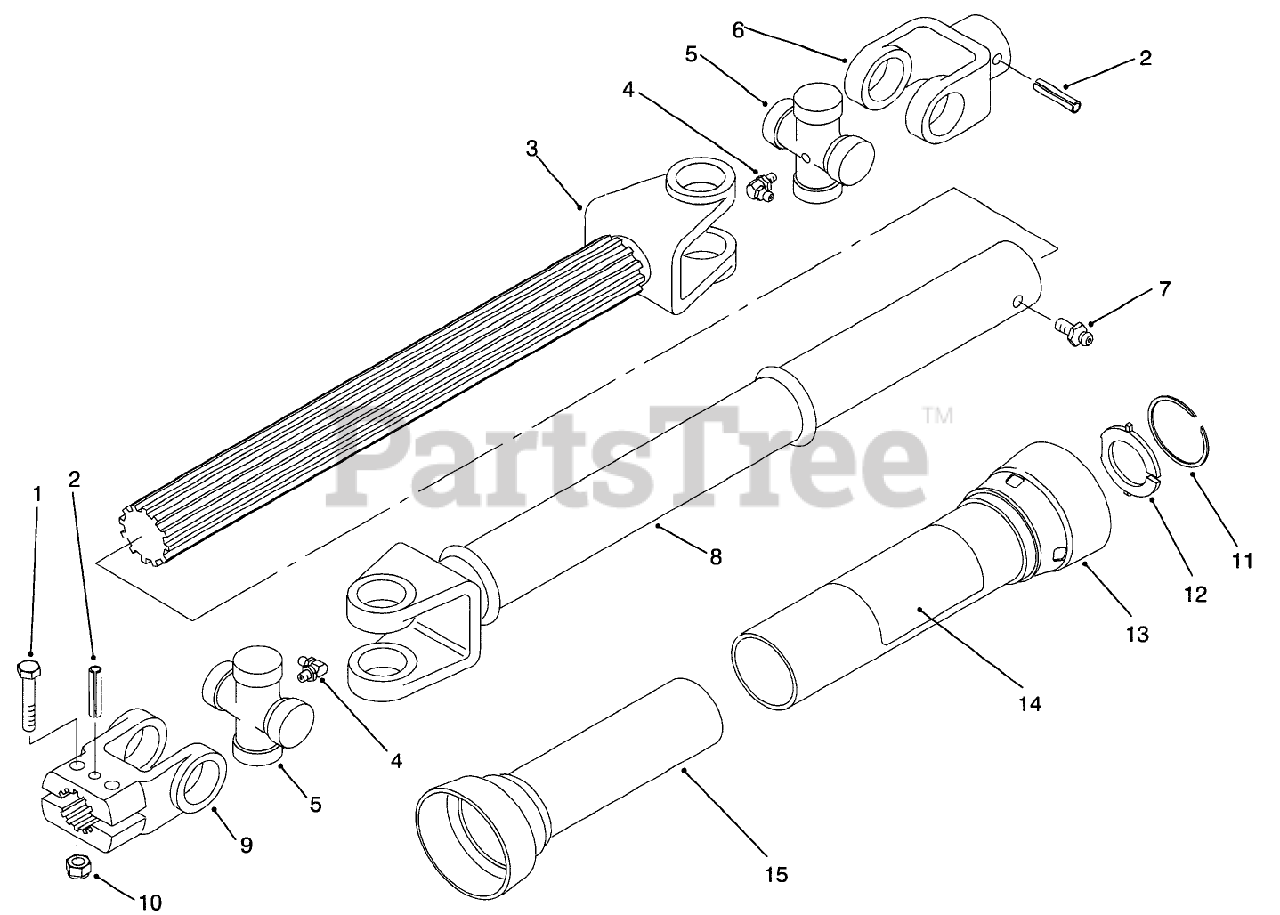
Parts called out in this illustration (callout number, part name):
1	SCREW-HH
2	PIN-ROLL
3	SHAFT-YOKE, SLIP
4	FITTING-GREASE
5	U-JOINT KIT
6	YOKE-END
7	FITTING-STRAIGHT
8	TUBE-SLIP YOKE
9	YOKE-END
10	NUT-LOCK, NI
12	Bushing-Nylon
13	Assembly-Guard, Outer (Incl. Ref. #11-12 & 14)
14	DECAL-DANGER
15	Assembly-Guard, Inner (Incl. Ref. #11-12)
